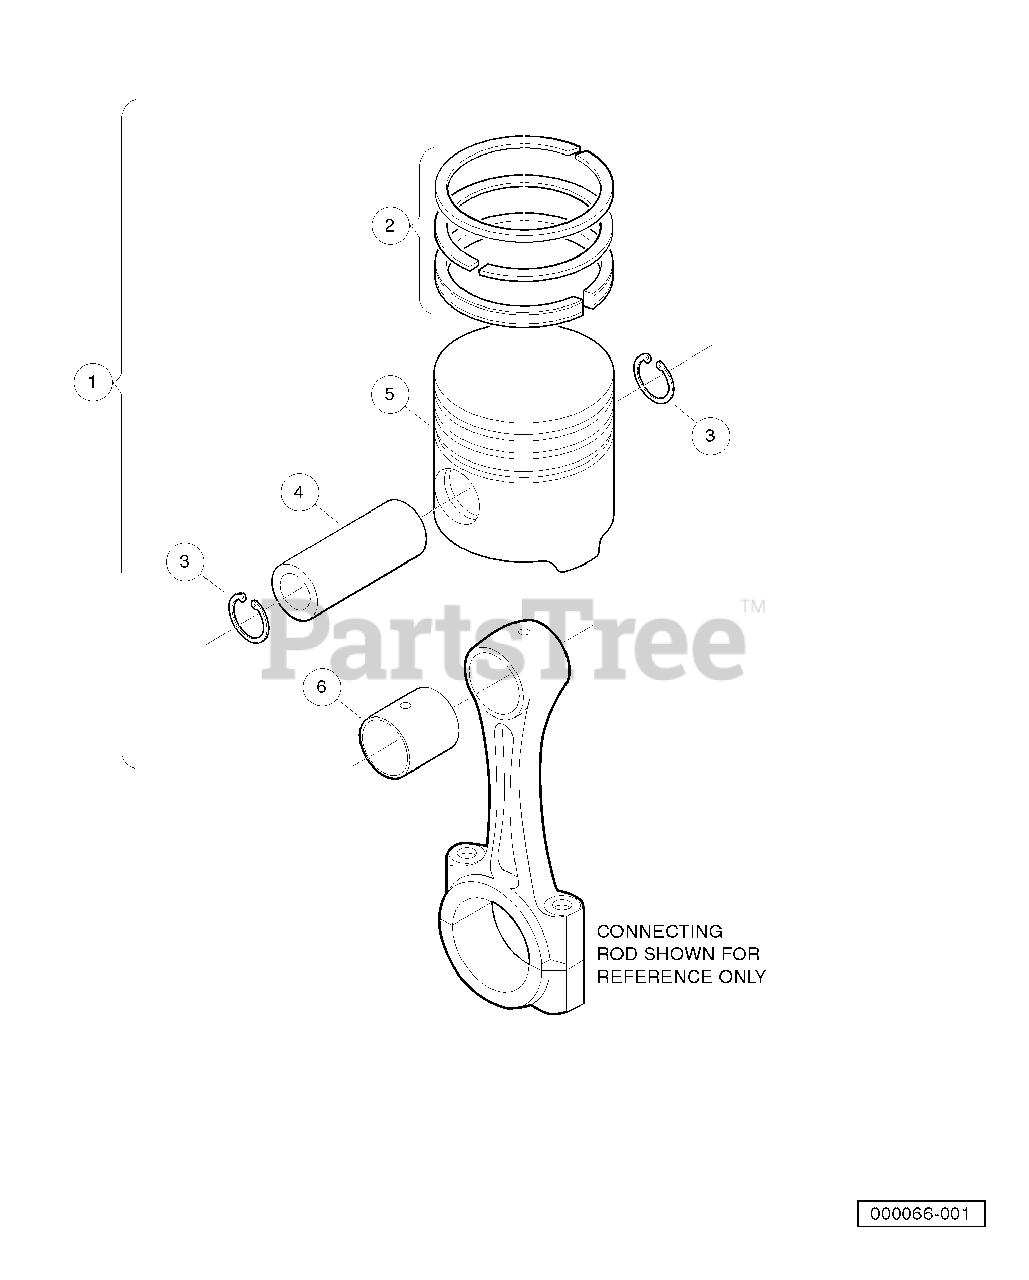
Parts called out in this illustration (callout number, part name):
1	Kit, Piston Rebuild, D722
2	Assy Piston Ring, D722 Std
3	Circlip, Piston Pin
4	Pin, Piston
5	Piston, D722, Std
6	Bushing, Piston Pin, D722
